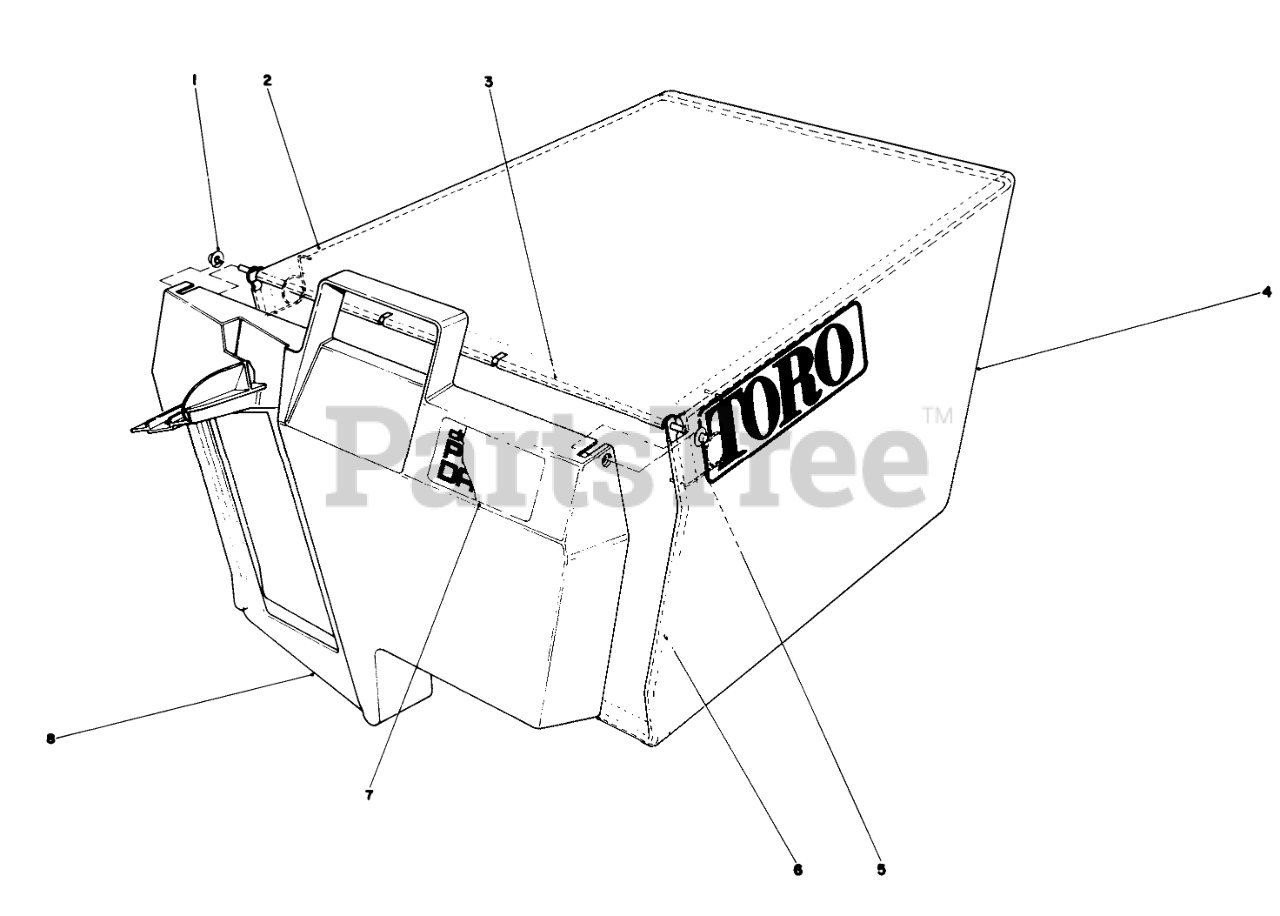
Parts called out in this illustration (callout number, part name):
1	NUT-PUSH
2	FRAME-BAG, UPPER
3	HINGE-DOOR, BAG
4	Bag
5	SPRING
6	FRAME-BAG
7	BAG DOOR DECAL
8	Door Grass Bag
